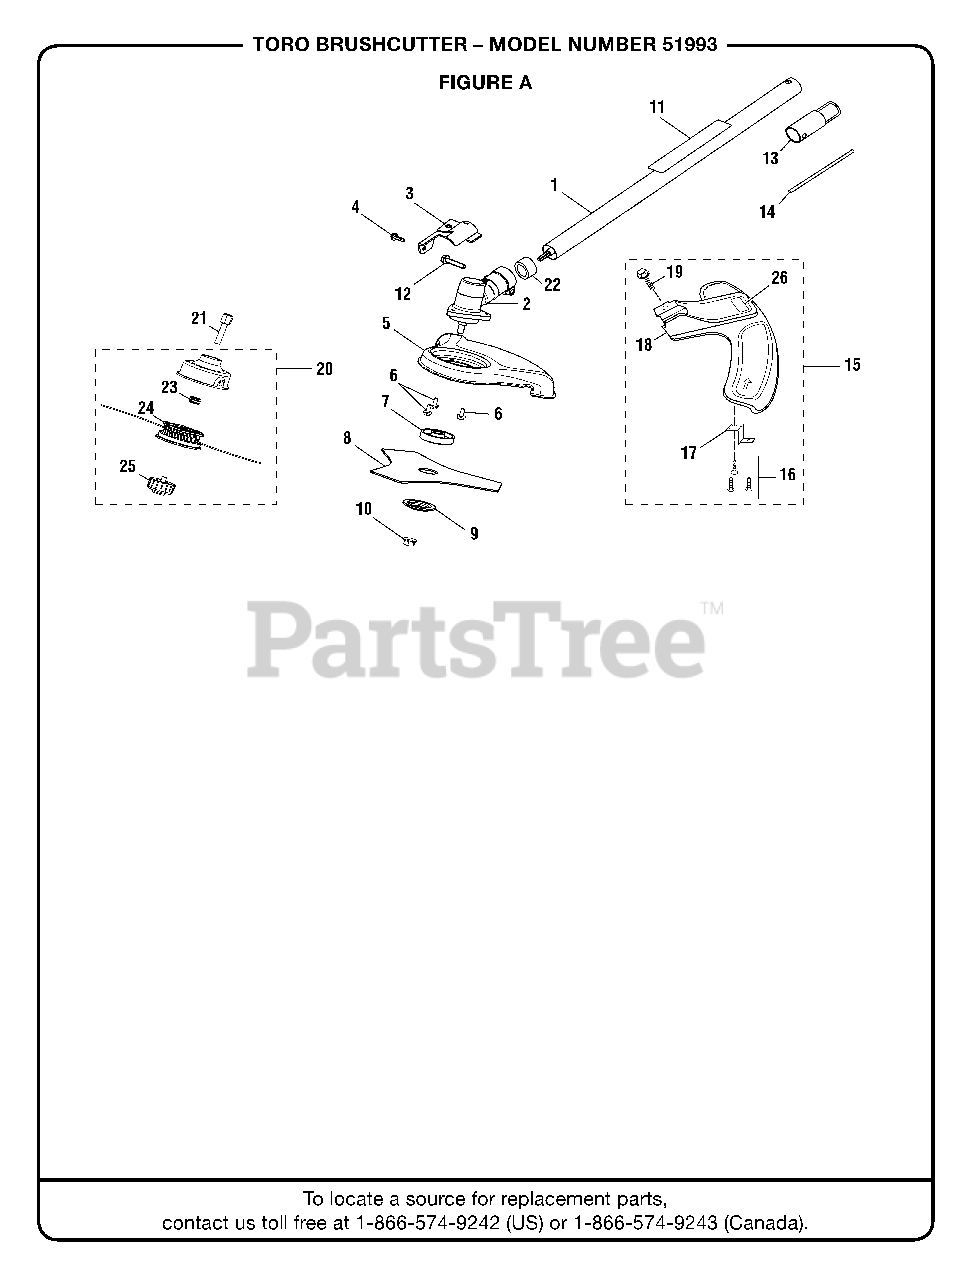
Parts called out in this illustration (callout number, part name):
1	STRAIGHT SHAFT ASSEMBLY
2	GEAR CASE ASSEMBLY
3	GRASS DEFLECTOR CLAMP
4	SCREW (#10-24 X 5/8 in. HEX WASHER HD.)
5	BLADE GUARD
6	SCREW (#10-24 X 1/2 in. SLOTTED HEX HD.)
7	FLANGED WASHER
8	BLADE (TRI-ARC(TM))
9	CUPPED WASHER
10	BLADE NUT, LEFT-HANDED THREADS
11	WARNING LABEL
12	SCREW (1/4-20 X 1-1/4 in.)
13	HANGER CAP
14	HEAD LOCKING TOOL
15	GRASS DEFLECTOR ASSEMBLY
17	LINE CUTTING BLADE
18	GRASS DEFLECTOR
19	SCREW (#1/4-20 X 1-1/4 in. HEX WASHER HD.)
20	TRIMMER HEAD ASSEMBLY (.095)
21	TRIMMER HEAD SHAFT ADAPTOR
23	COMPRESSION SPRING
24	SPOOL WITH LINE (.095)
25	RETAINING CAP, LEFT-HANDED THREAD
26	GRASS DEFLECTOR LABEL
